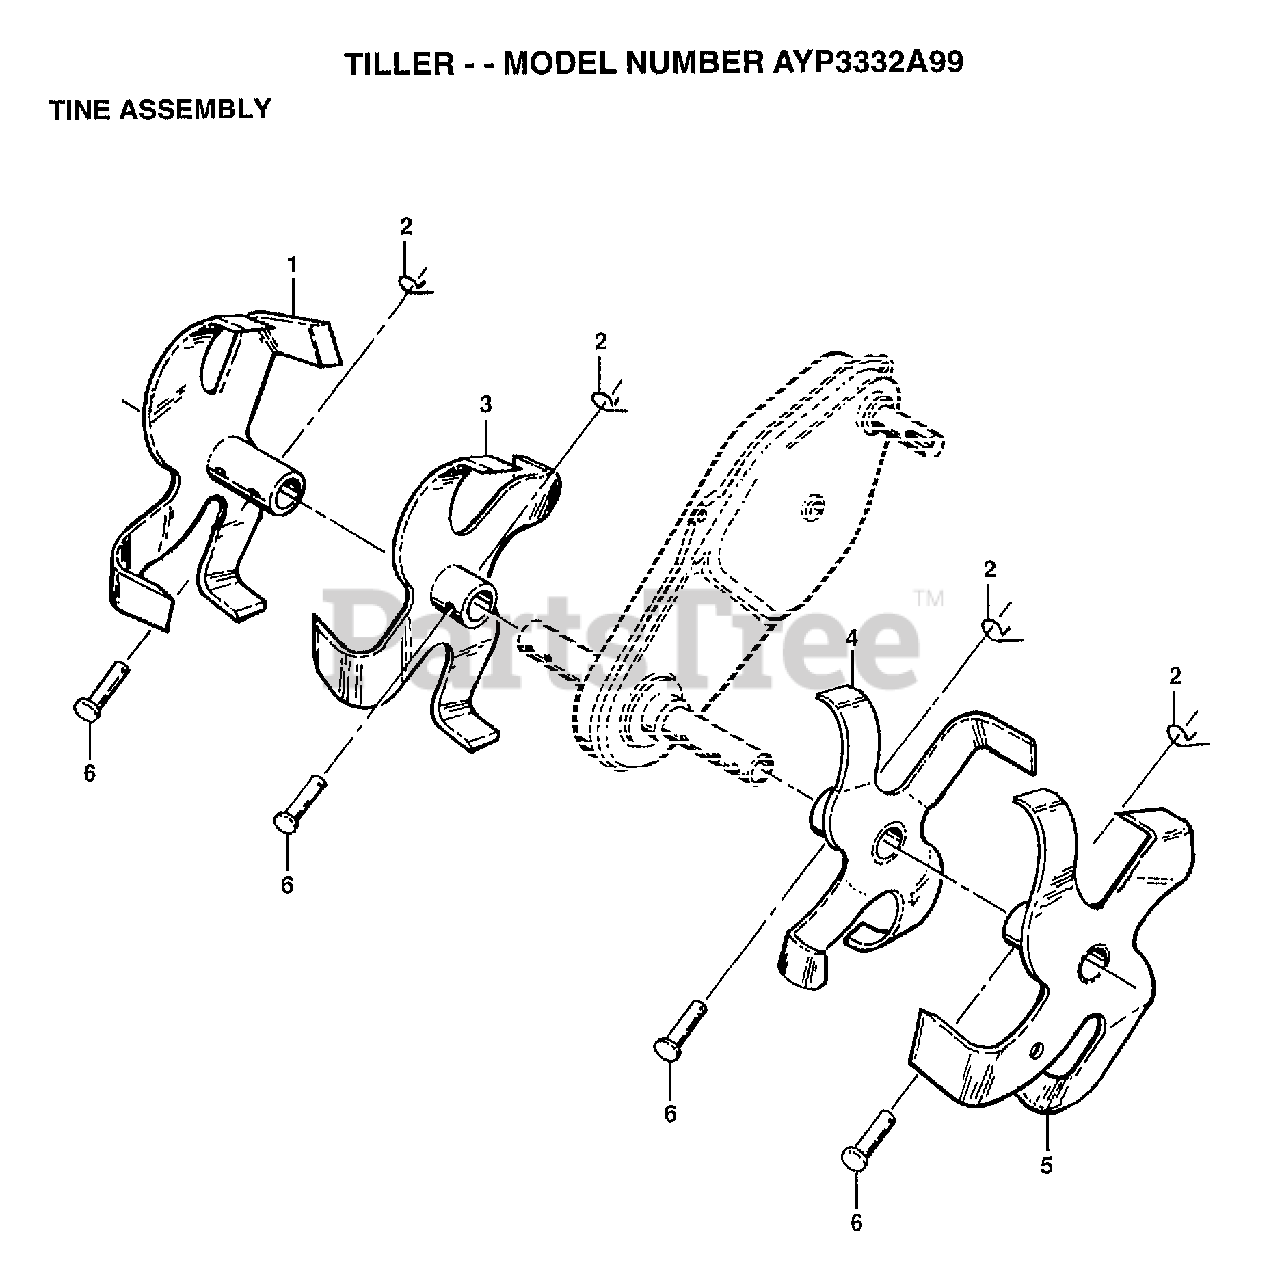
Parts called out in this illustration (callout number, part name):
1	"TINE.ASM.OUTER.RH.12"""
2	SPRING.RETAINER
3	"TINE.ASM.INNER.RH.12"""
4	"TINE.ASM.INNER.LH.12"""
5	"TINE.ASM.OUTER.LH.12"""
6	DRILLED RIVET RT
